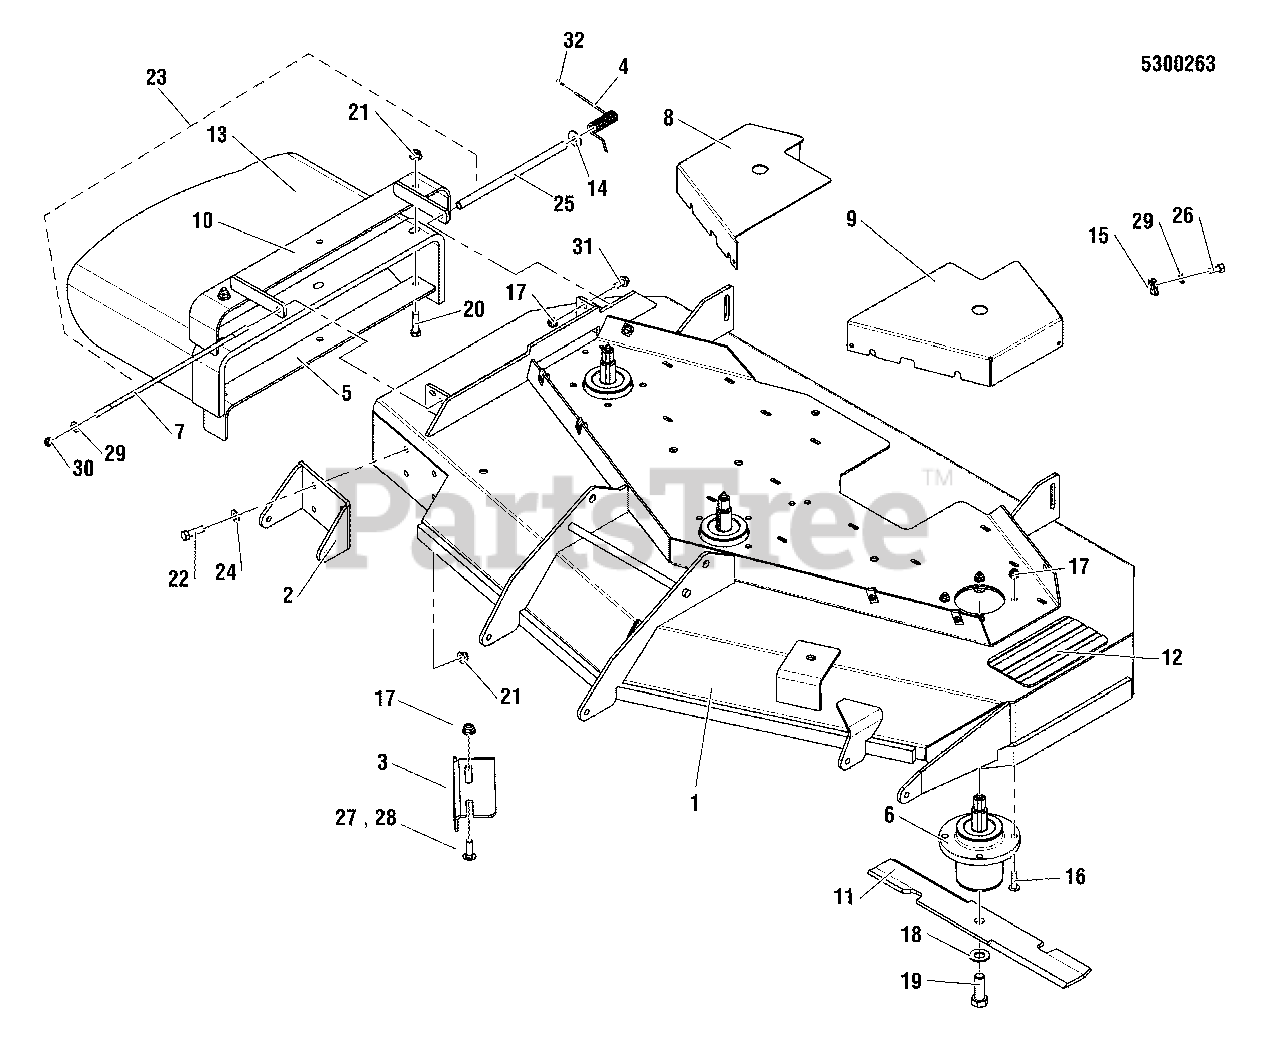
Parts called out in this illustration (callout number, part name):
2	PLATE, BRACKET, ANTI SCALP - ORANGE
4	SPRING, TORSION
5	SUPPORT, DISCHARGE CHUTE - BLK
6	ASSM, SPINDLE, LOW PROFILE
7	ROD MOUNT, CHUTE
8	GUARD, 52" DECK - RH - ORG
9	GUARD, 52" DECK - LH - ORG
10	WELD, FRAME, CHUTE, 61 - ORG
11	BLADE, 18 X .25 X 2.5, 1 X 3.5 (SET OF THREE)
11	BLADE, 18 X .25 X 2.5, 1 X 3.5
12	SAFETY WALK, 4.00 X 7.50
13	CHUTE, DISCHARGE, BEND RUBBER
14	WASHER, 5/16 FENDER
15	BODY CLIP, 5/16-18-7GA MATERIAL
16	BOLT, 5/16-18 X 1 1/4 FLANGE
17	NUT, 5/16-18 HEX NYLOCK FLANGE
18	WASHER, 5/8 GRADE 8, YZ
19	BOLT, 5/8-11 X 1-3/4 GD8
20	BOLT, 3/8-16 X 1-1/2 GD5 YZ
21	NUT, 3/8-16 HEX NYLOCK FLANGE
22	BOLT, 3/8-16 X 1-1/4 GD5 YZ
23	ORDER INDIVIDUAL PIECES TO SERVICE DISCHARGE CHUTE COMPONENTS
24	WASHER, 3/8 SAE
25	SPACER, TORSION SPRING,9.63 LG
26	BOLT, 5/16-18 X 3/4 GD5
27	BOLT, 5/16-18 X 3/4, CARRIAGE
28	BOLT, 5/16-18 X 1, CARRIAGE
29	WASHER, 5/16" SAE
30	NUT, 5/16-24 HEX NYLON LOCK
31	SCREW-HEX WZ LOCK FLNG 5/16-18X0.750BLK
32	CAP, PROTECTOR, .120 ID
